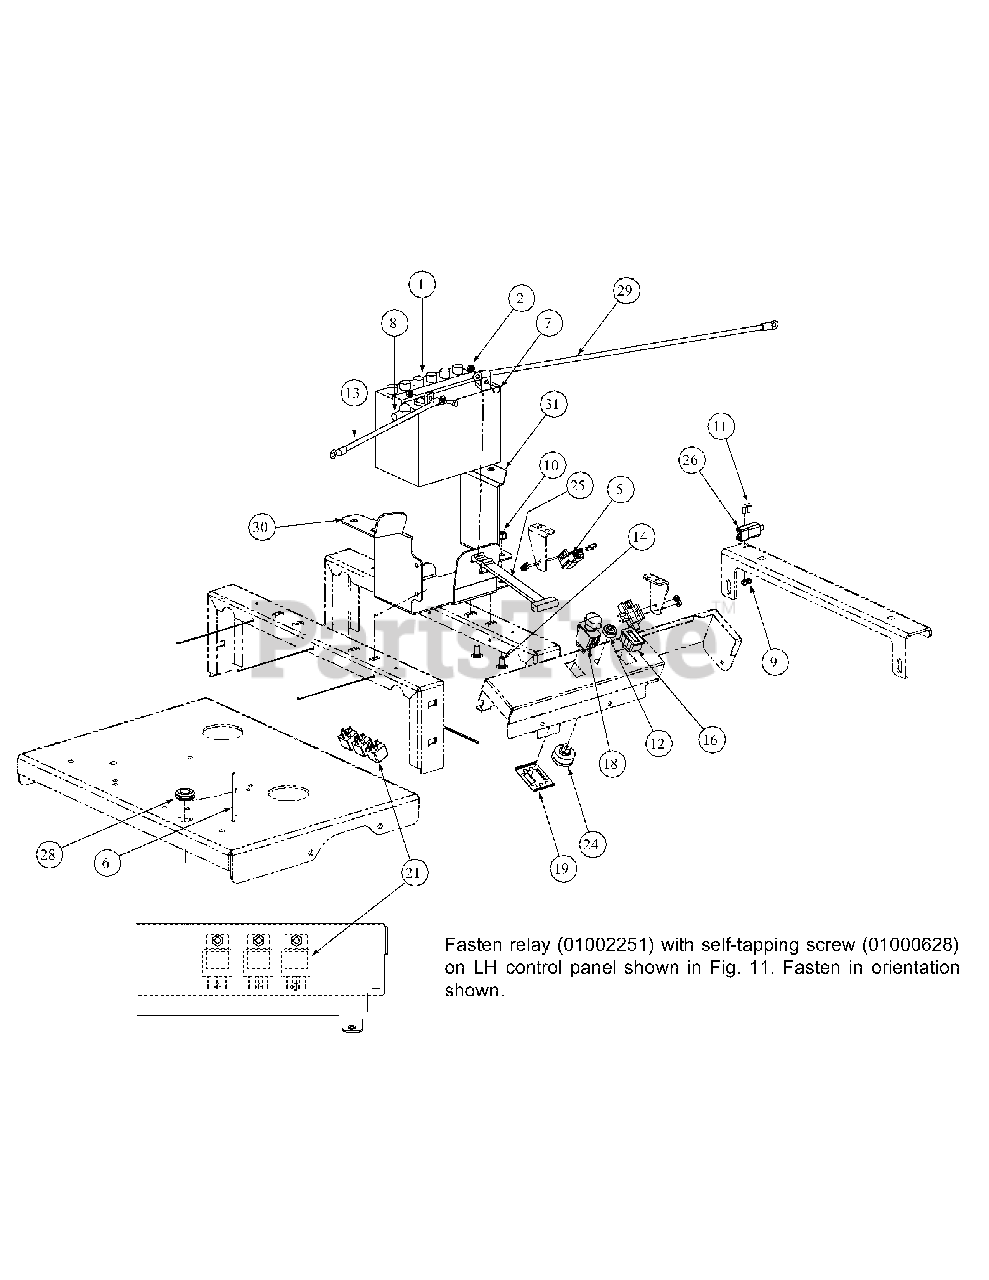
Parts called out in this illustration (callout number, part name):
1	Battery, 12V 225CCA 30 Min
2	Lock Nut, 1/4-20
5	Switch, Safety
6	Tie, Cable, 3/16 x .05 x 7.4"
7	Screw, Hex, Cap, 1/4-20 x .75
8	Boot, 1" OD Rubber Battery-PST, Red
9	Lock Nut, Nylon Insert
10	Nut, Hex, Flange Lock, 3/8-16
11	Screw, Phillips Head, Machine, 10-32 x 5/8
12	Nut, W/Cap, 5/8-32 Ignition
13	Cable, Battery, Red, 36"
14	Carriage Bolt, 3/8-16 x .75 LG.
16	Meter, Hour (Honda)
18	Switch, Electric, PTO
19	Bracket, PTO Switch Retainer
21	Relay, 12V 40A
24	Switch, Ignition, 6 Pin
24	Key, Ignition
25	Strap, Battery
26	Switch, Plunger
28	Grommet, .75 ID
29	Cable, Battery Red, 28"
30	Mount Bracket, Battery
31	Mount Bracket, Battery
